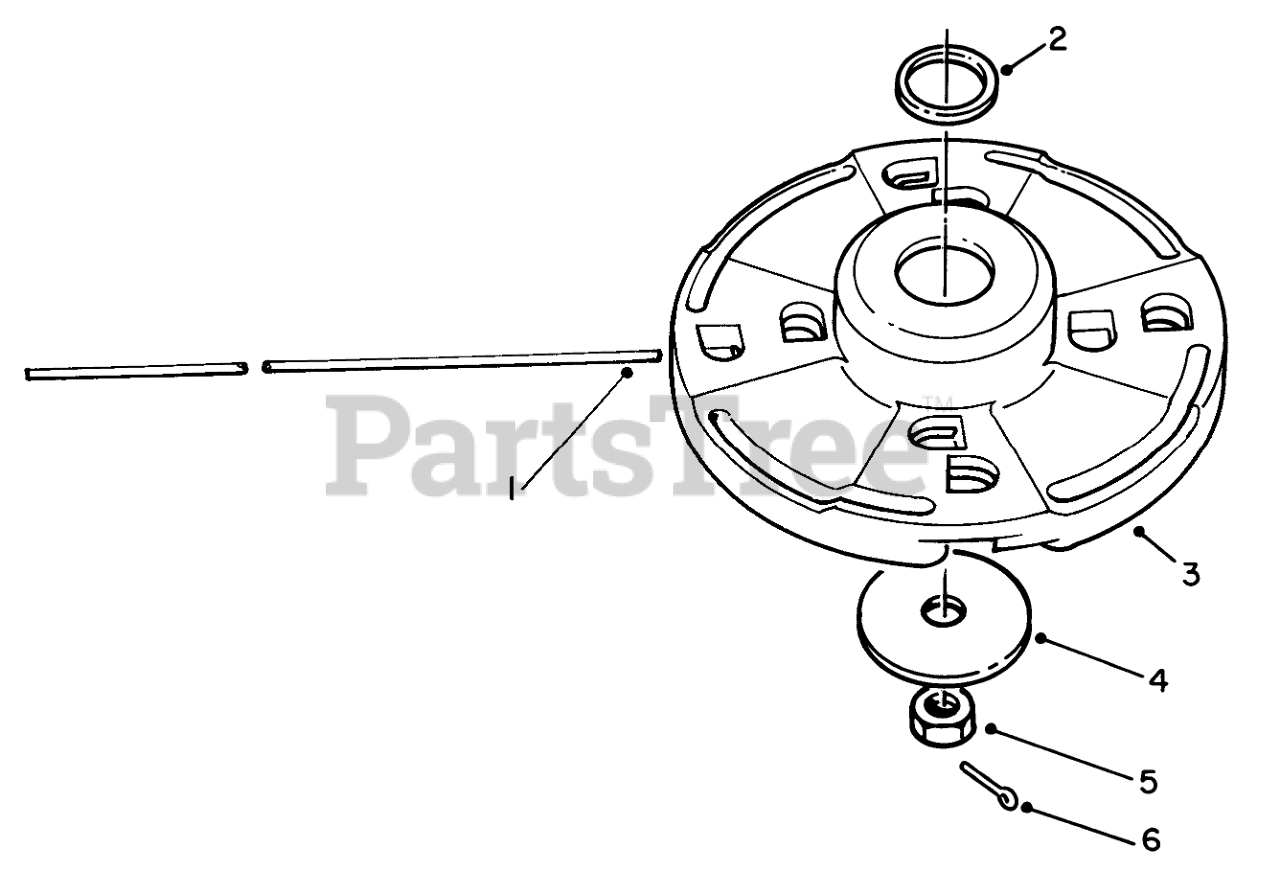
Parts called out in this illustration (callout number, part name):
1	LINE PACK (100)
2	SPACER
3	Head Assembly (Incl. Ref. #2)
4	WASHER
6	1/16 X 1 LG COTTER PIN
